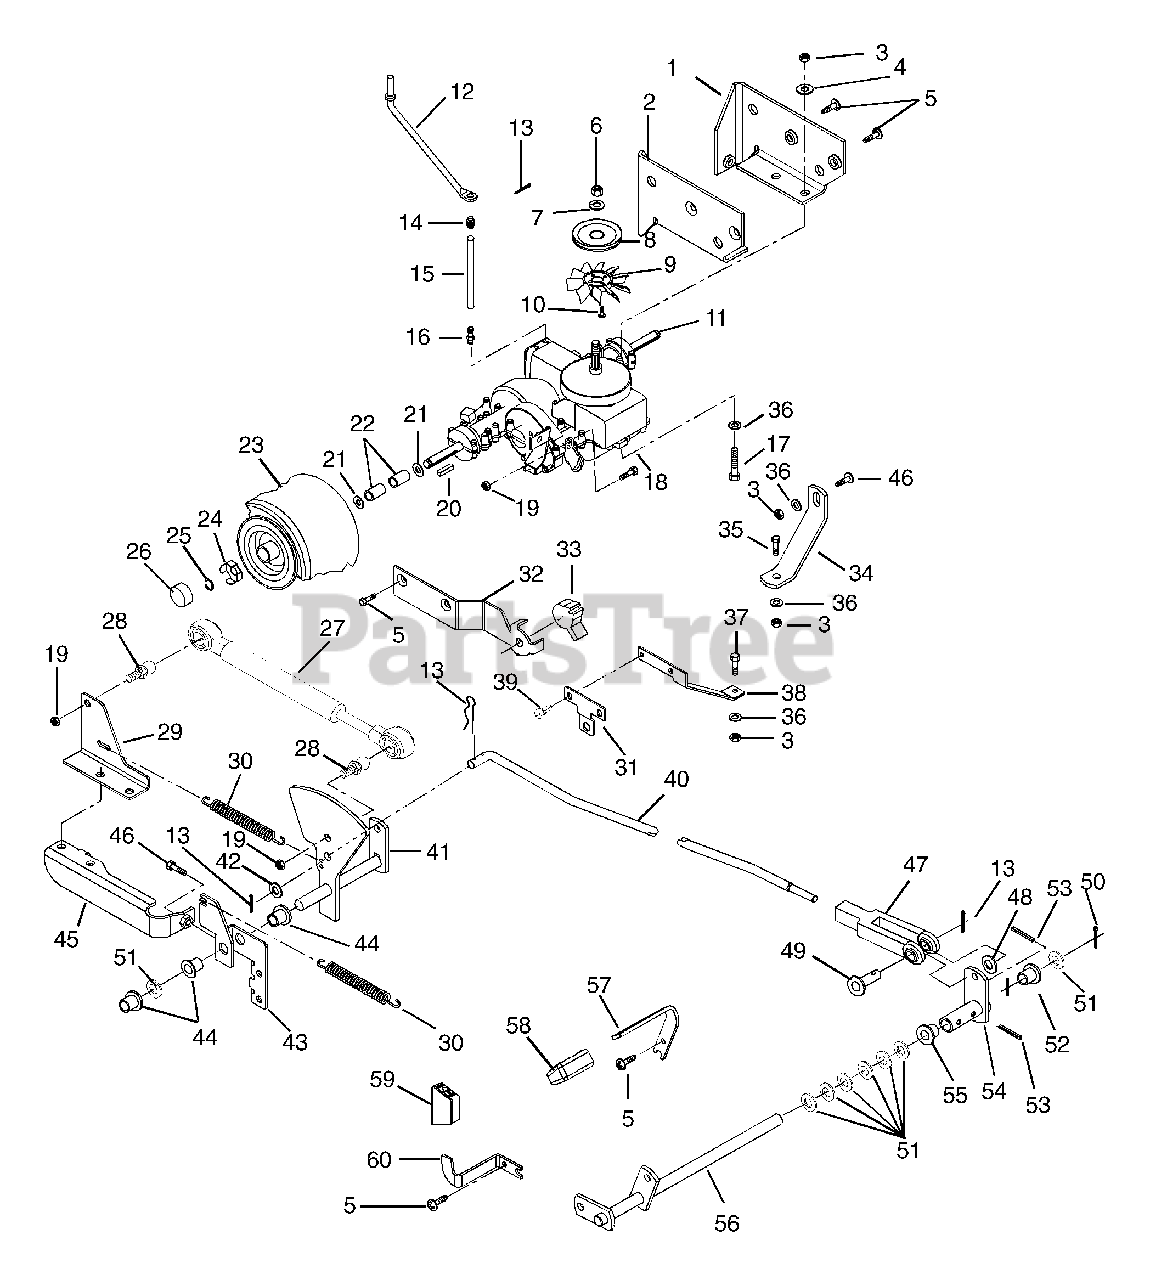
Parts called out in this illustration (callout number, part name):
1	TRANS MOUNT, LH
1	MOUNT - TRANS. LH
2	TRANS MOUNT, RH
2	MOUNT - TRANS. RH
3	@NUT-LK-CTR .31-18 YWZC
4	WSHR-FL-STL .328X.875X.062YWZC
5	@SCR-TAP .38-16X1.00 HWH TR YZ
6	NUT-JAM .50-20 GR2 YWZC
7	@WSHR-LK .50X.125 REG YWZC
8	SHEAVE - TRANSAXLE
10	SCR-TAP 10-24X.484 HWH TR
11	TRANSAXLE- HYDRO #325-0750
12	ROD, TRANS DISCONNECT
12	ROD - TRANS. DISCONNECT
13	@PIN-CTR .09X.75 EXTPRSQCT YWZ
14	CAP-VENT .50
15	HOSE- VENT .50ID X 7.50LONG
16	FTG-STR .50 O-RING
17	@BLT-HEX .31-18X2.50 GR5 YWZC
18	@BLT-HEX .31-18X.75 GR5 YWZC
19	@NUT-LK-CTR .31-18 YWZC
20	KEY-SQ .188X2.0X.188 SAE 8630
21	WSHR-FL-STL.755X1.375X.062YWZC
22	BSHG-SLV .750X1.125X1.062
23	TIRE ASSEMBLY 20 X 10.00-8
23	RIM-SIERRA
23	TIRE 20X10-8 2P TS TL
24	SPINDLE CUP
25	RG-RTNG-EXT .750X.050
26	HUB CAP
27	DAMPER - HYDRAULIC
28	STUD- BALL
29	ANCHOR - SPRING - TOP
30	SG-TENS .085X.60X5.13 WLD8.3
31	SUPPORT, SHIFT ARM
31	SUPPORT - SHIFT ARM
32	MOUNT - MAGNET
34	STRAP, TORQUE L.H (HYDRO)
34	STRAP - TORQUE L.H.
35	@BLT-HEX .31-18X1.50 GR5 YWZC
36	@WSHR-FL-STL.344X.688X.065YWZC
37	@BLT-HEX .31-18X2.25 GR5 YWZC
38	STRAP, TORQUE R.H (HYDRO)
38	STRAP - TORQUE RH
39	SCR-TAP .312-18X.50 HWH TR BL
40	ROD, SHIFT
40	ROD - SHIFT
41	ARM, SHIFT (WELDMENT)
41	ARM - SHIFT
42	@WSHR-FL-STL.406X.812X.065 YWZ
43	PIVOT - REVERSE
44	BSHG-FLG .508X.645X.459X.75 NY
45	ANCHOR - SPRING - BOTTOM
46	@BLT-HEX .31-18X.75 GR5 YWZC
47	YOKE, .312-24 X 2.25
48	WSHR-FL-STL .390X.75X.125 YWZC
49	PIN-CLEV .312X.822 HDND PL
50	@PIN-CTR .12X1.00 EXTPRSQCT YZ
51	WSHR-FL-STL .52X.827X.062 YWZC
52	BSHG-FLG .515X.750X.745X1.00NY
53	PIN-GRV .188X1.25 TP A
54	ARM & HUB
55	BSHG-FLG .502X1X.750
56	SHAFT - PEDAL
57	PEDAL - FORWARD
58	COVER - PEDAL - FORWARD
59	COVER - PEDAL - REVERSE
60	PEDAL - REVERSE
